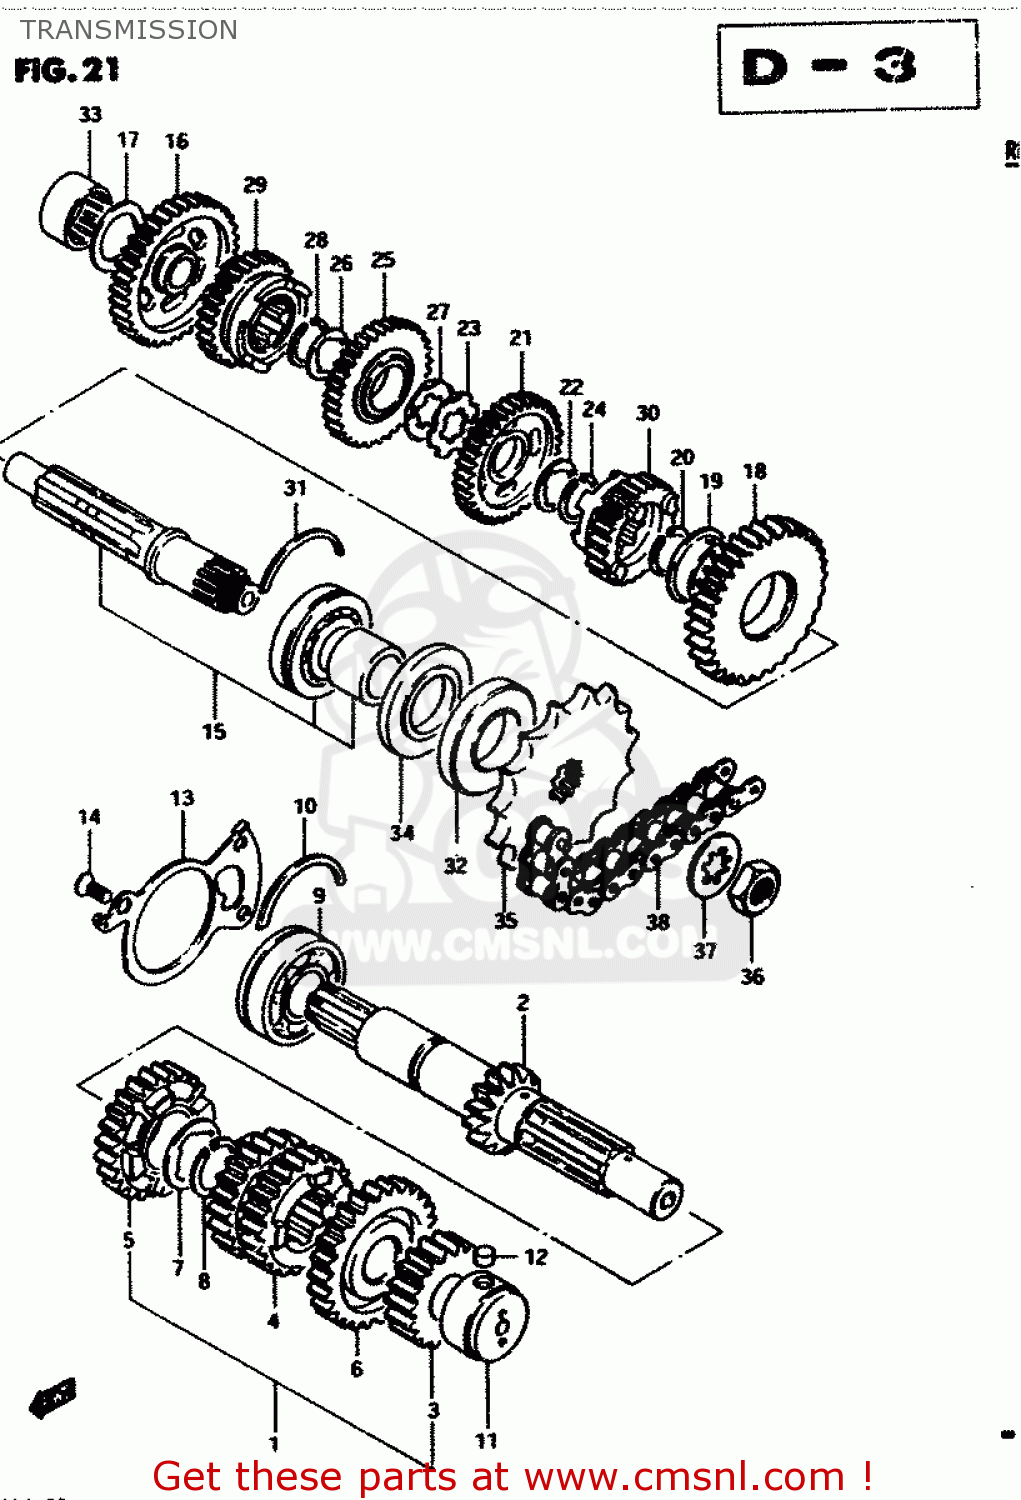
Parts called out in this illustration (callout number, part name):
1	SHAFT,COUNTER
2	SHAFT,COUNTER
3	GEAR,2ND DRIVE(NT:18)
4	GEAR,THIRD DRIVE
5	GEAR,FIFTH DRIVE
6	GEAR,SIXTH DRIVE
7	WASHER
8	CIRCLIP
9	BEARING(25X62X17)
10	C-RING
11	ROLLER BEARING (20X34X2
12	PIN
13	PLATE,COUNTERSHAFT BEARING
14	SCREW
15	SHAFT,DRIVE
16	GEAR,FIRST DRIVEN
17	WASHER
18	GEAR,SECOND DRIVEN
19	BUSHING
20	CIRCLIP
21	GEAR,THIRD DRIVEN
22	WASHER,LOCK
23	WASHER,LOCK
24	CIRCLIP
25	GEAR,FOURTH DRIVEN
26	WASHER,LOCK
27	WASHER
28	CIRCLIP
29	GEAR,5TH DRIVEN(NT:25)
30	GEAR,SIXTH DRIVEN
31	C-RING
32	SEAL,OIL(32X62X7)
33	ROLLER BEARING (20X34X1
34	SEAL,OIL(32X62X5.5)
35	SPROCKET,ENGINE(NT:16)
36	NUT
37	WASHER
38	CHAIN ASSEMBLY,DRIVE
